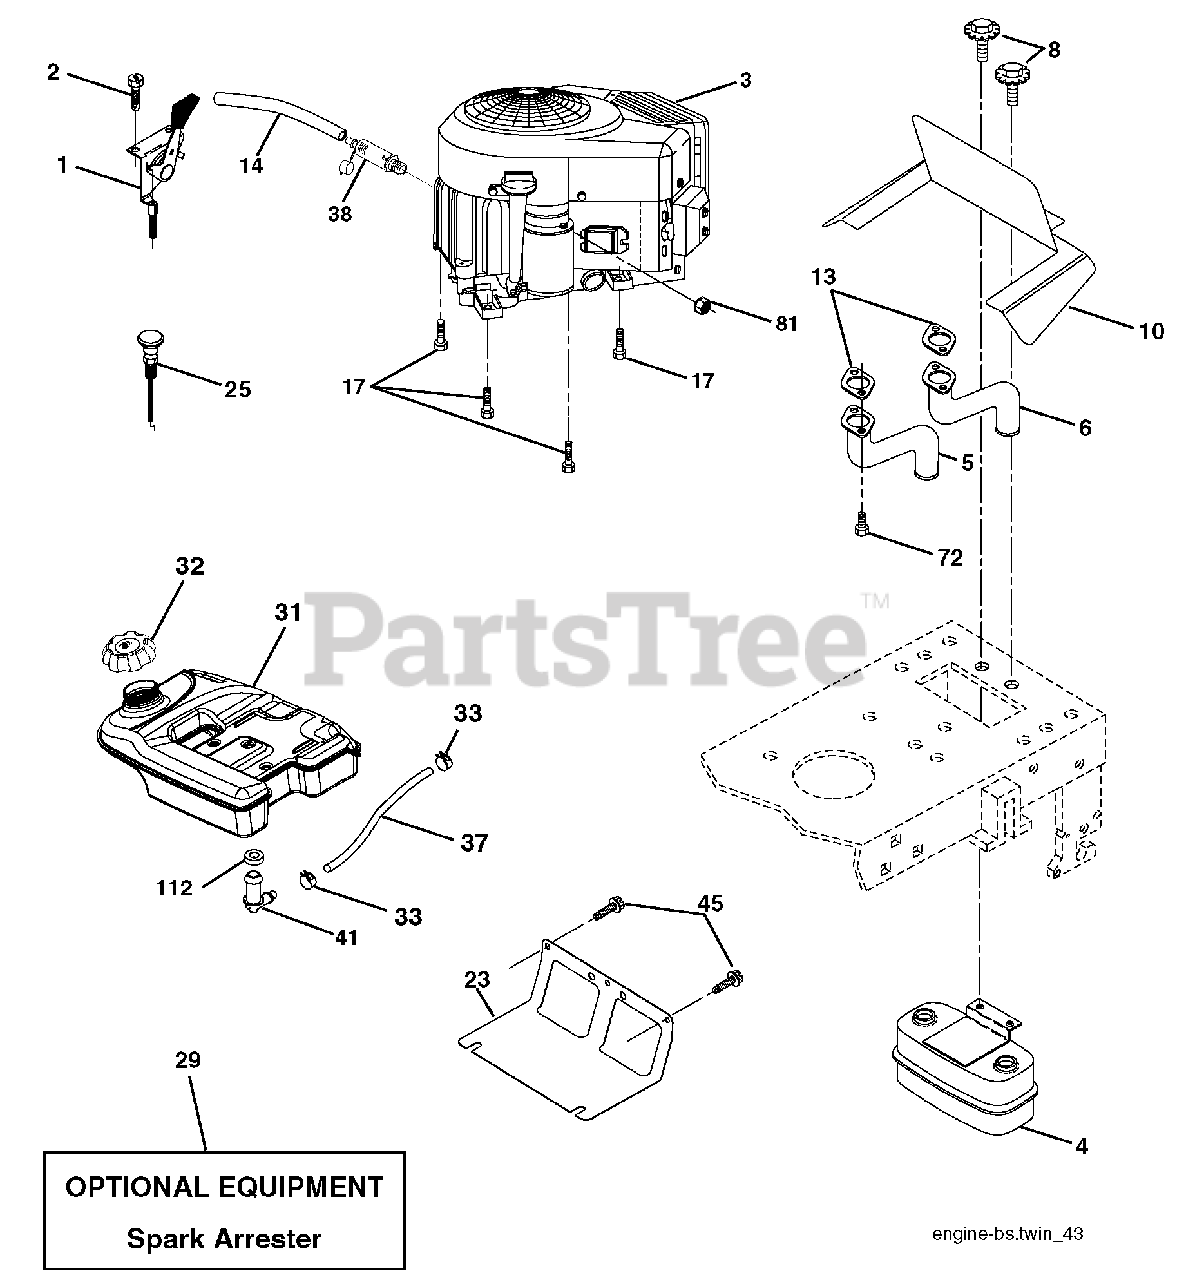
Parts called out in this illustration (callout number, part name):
1	Control, Throttle/Choke
2	Screw Hex Single Lead 10 x 3/4
4	Muffl er
5	Tube Exhaust LH
6	Tube Exhaust RH
8	Bolt 5/16-18 unc x 3/4 w/Sems
10	Shield Heat Muffl er
13	Muffl er Gasket
14	Tube Oil Drain
17	Screw 3/8-16 x 1-1/2
23	Shield, Browning/Debris Guard
29	Arrester, Spark
31	Tank, Fuel
32	Cap Gauge, Fuel
33	Clamp, Hose Blk
37	Line, Fuel
38	Plug Drain Oil Easy
41	Stem Tank Fuel
45	Screw Hex Wsh Thdrol 3/8-16 x 3/4
72	Screw 5/16-18 x 1
81	Nut Keps Hex 1/4-20 unc
112	Bushing
